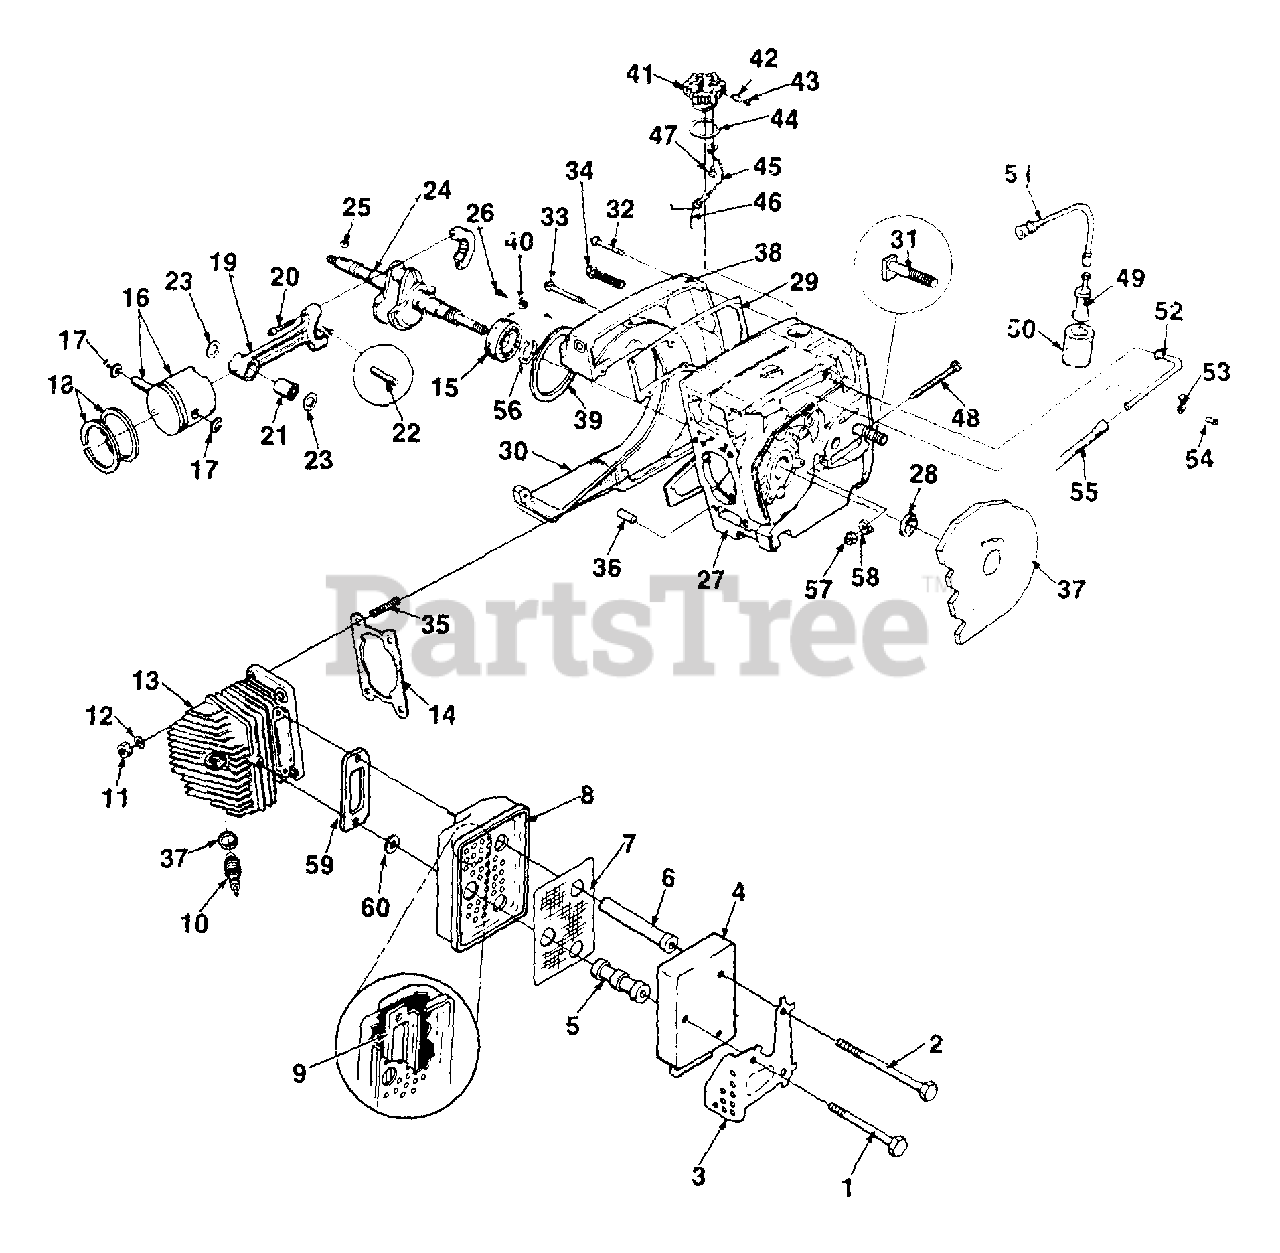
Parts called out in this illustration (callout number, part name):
2	SCREW-Hex hd. 1/4-20 x 3
3	SHIELD-Muffler
4	CAP-Muffler
5	SUPPORT-Short
6	SUPPORT-Long
7	SCREEN-Spark arrestor
8	BODY-Muffler
9	PLATE-Muffler
10	SPARK PLUG
11	NUT 1/4-28
12	WASHER-Lock 1/4
13	CYLINDER
14	GASKET-Cylinder
15	BEARING
16	PISTON & PIN ASSEMBLY
17	PISTON PIN RETAINING RING
18	PISTON RING
19	ROD-Connecting
21	BEARING
22	BEARING-Needle
24	CRANKSHAFT
25	KEY
26	SCREW-Torx 10-32
27	CRANKCASE
28	SEAL
29	GASKET-Oil cover
30	COVER-Fuel tank
32	SCREW-Fil hd. 8-32 x 5/8
33	SCREW-Fil hd. 8-32 x 1 3/4
34	SCREW-Fil hd. 8-32 x 2 3/16
35	STUD-Cylinder
36	PIN-Dowel
37	SHIELD-Sawdust
38	LABEL-Warning
39	"O" RING
40	WASHER-Lock
41	CAP-Fuel
42	VALVE-Check
44	GASKET-Fuel cap
46	RETAINER-Cap
49	FILTER-Fuel
50	FILTER ELEMENT
51	FUEL LINE
52	CONNECTOR
54	SCREW-Pan hd 6-32 x 5/16
55	FUEL LINE
56	RING-Retaining
57	NUT-Hex 1/4-20
58	ADJUSTING PIN
59	GASKET-Muffler
